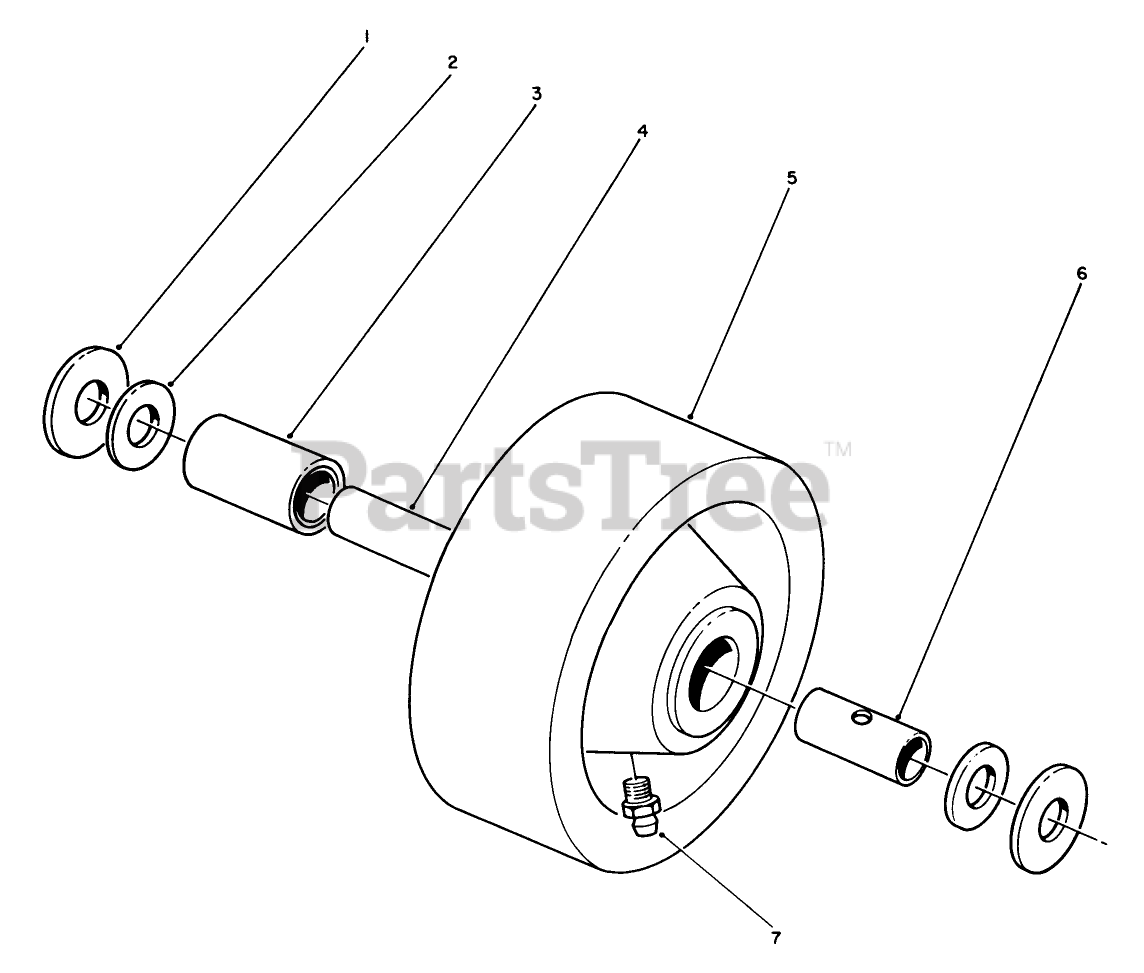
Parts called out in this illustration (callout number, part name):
1	THRUST WASHER
2	BEARING RETAINER
3	ROLLER BEARING
4	SPANNER-TIRE
5	WHEEL
6	SPANNER BUSHING
7	FITTING-GREASE
